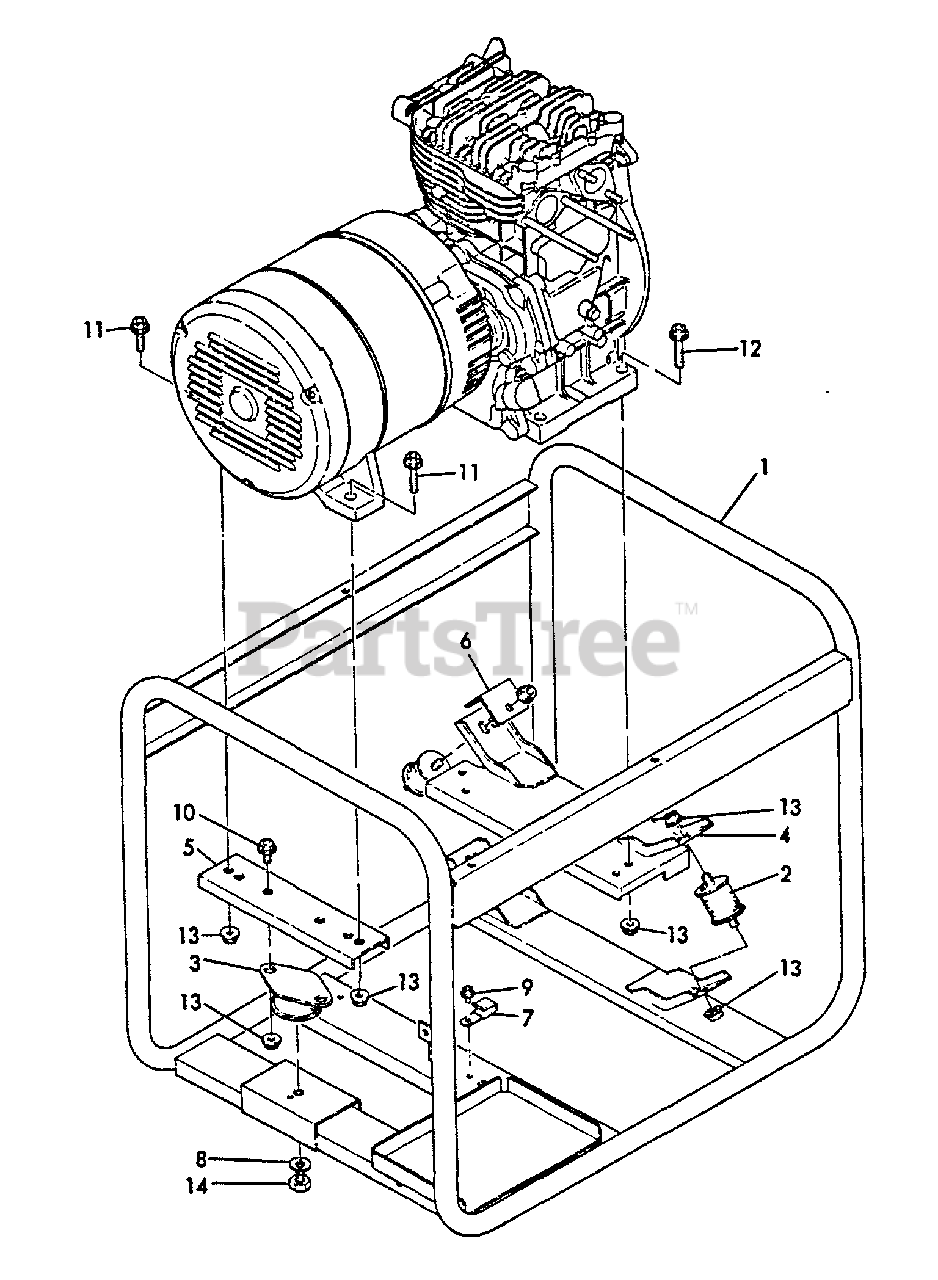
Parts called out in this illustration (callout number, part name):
1	FRAME
2	DAMPER, FRONT
3	DAMPER, REAR
4	STAY, DAMPER
5	STAY, REAR DAMPER
6	COVER, DAMPER
7	CLAMP
8	LOCKWASHER - 10
9	BOLT - 6×8 -- PLATED
10	BOLT - 8×20 -- PLATED
11	BOLT - 8×30 -- PLATED
12	BOLT - 8×38 -- PLATED
13	U-NUT M8
14	NUT - 10
